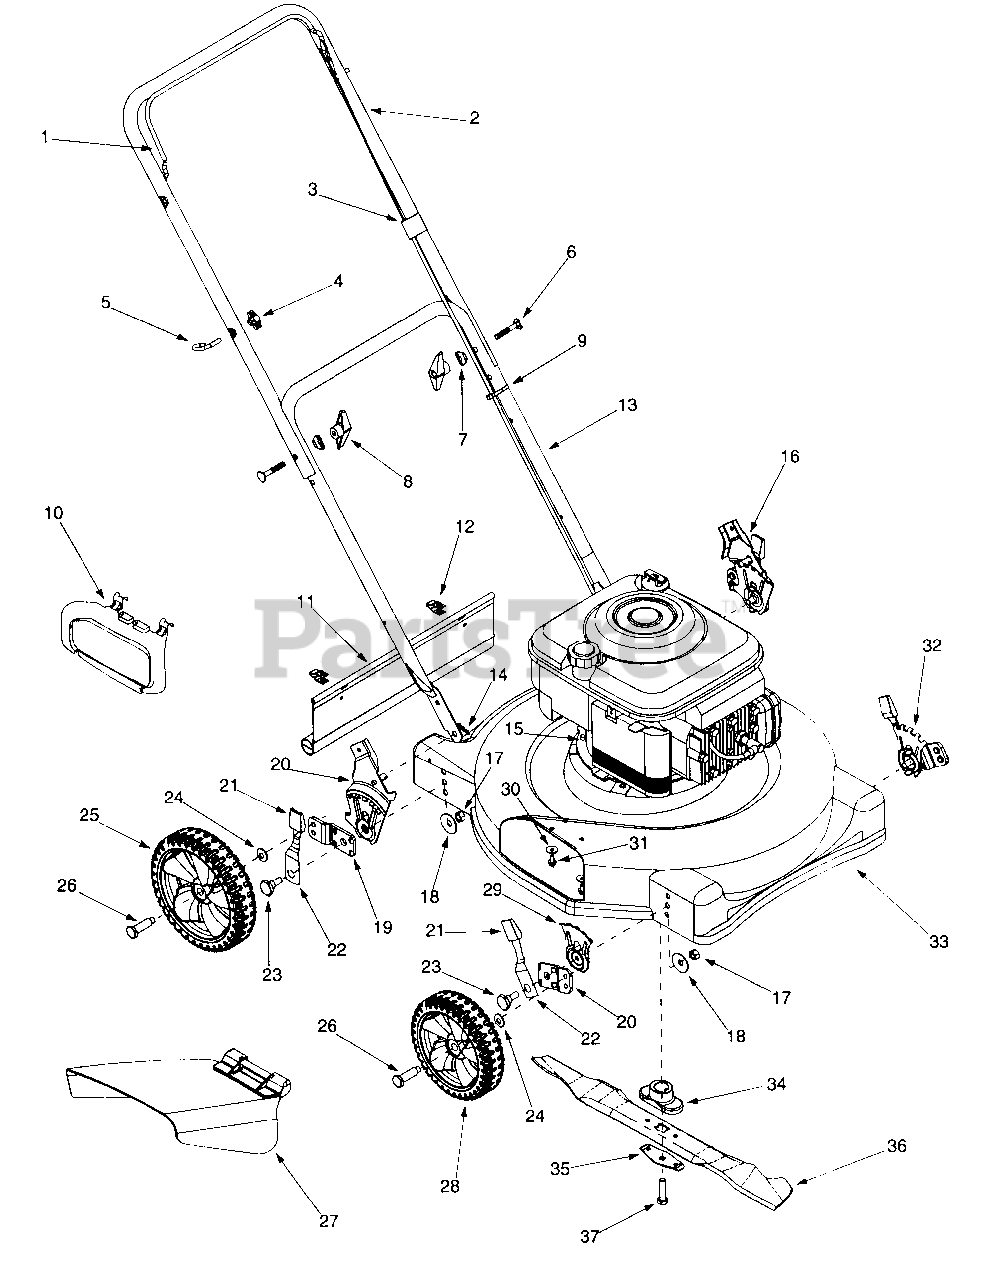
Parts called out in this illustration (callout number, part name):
1	Control Handle
3	Control Cable 37.25"
4	Handle Knob
5	Eye Bolt
6	Carriage Bolt
7	Shoulder Washer
8	Wing Nut
9	Cable Tie
10	Mulching Baffle
11	Trail Shield
12	Clip
14	Cotter Pin
15	Hex Washer Screw 3/8-16 x 1.0
18	Bell Washer .390 ID x .380 OD
19	Pivot Bar
20	Height Adj. Bracket LH
21	Height Knob
22	Spring Lever
23	Shoulder Screw
24	Spring Washer .401 ID x .870 OD
25	Wheel Assembly 8" x 1.8
26	Shoulder Screw
27	Discharge Chute Assembly
28	Wheel Assembly 7" x 1.8
29	Height Adjuster Plate
30	Bell Washer.265 ID x.75 OD
31	Hex Washer Screw 1/4-20 x .50
32	Height Adjuster Assembly LH
35	Blade Bell Support
36	22" Blade
37	Hex Cap Screw 3/8-24 x 1.50
